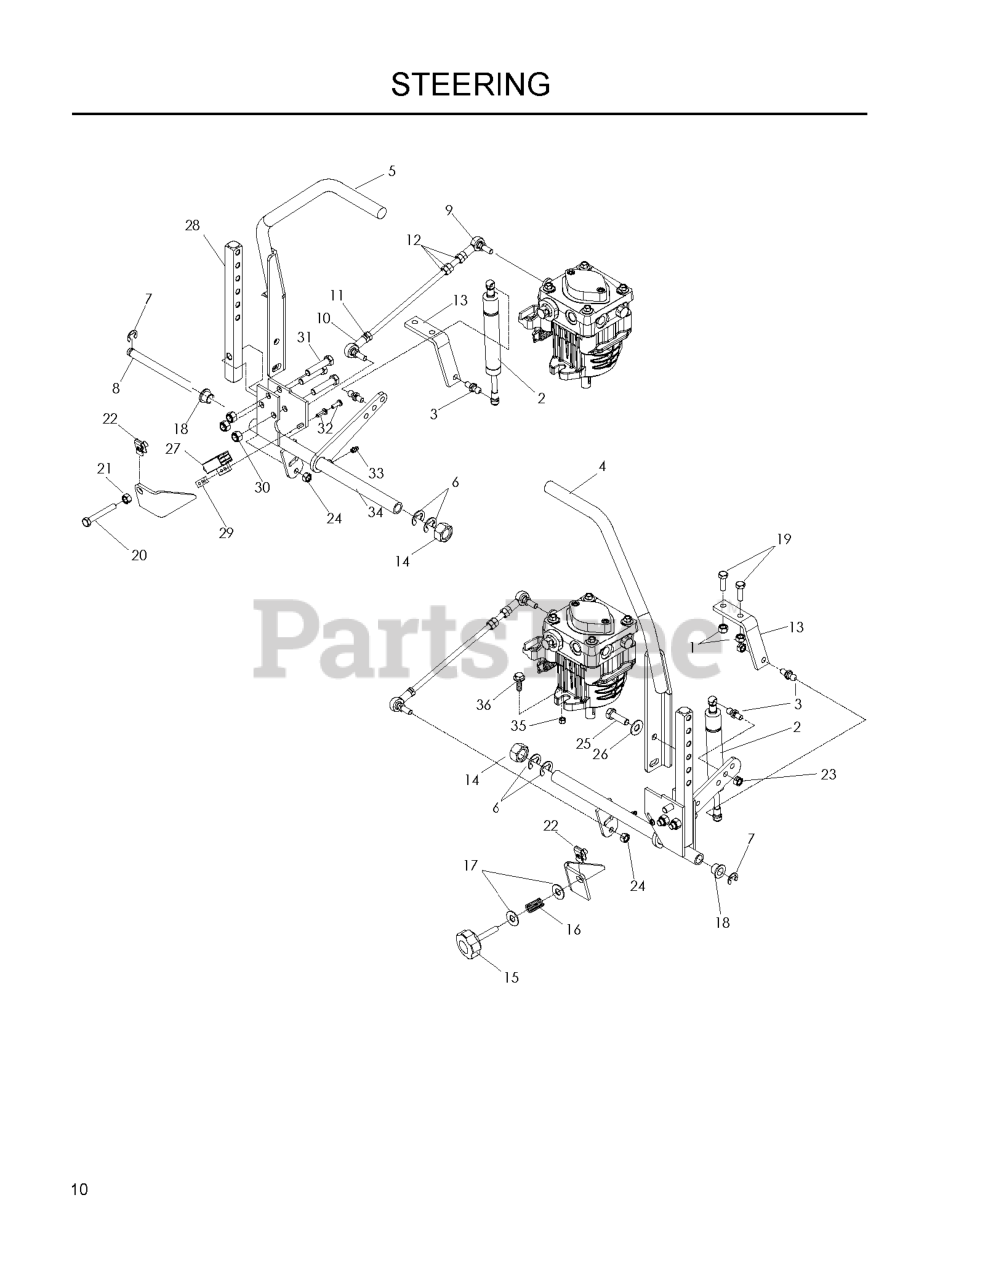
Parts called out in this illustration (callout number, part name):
1	NUT 5/16 NYLOC
2	DAMPENER W/EXT SEAL
3	STUD.BALL.10MM
4	ASSEMBLY, DRIVE LEVER LT
5	ASSEMBLY, DRIVE LEVER RT
6	E-RING 5/8
7	E-RING 1/2 (2 2)
8	CONTROL SHAFT
9	SPHERICAL ROD END, LH
10	SPHERICAL ROD END, RH
11	NUT 5/16F LEFTHAND
13	DAMPENER BRACKET
14	NUT 3/4 X 16 HEX CTR
15	ADJUSTMENT KNOB
16	COMPRESSION SPRING
17	WASHER 5/16 FLAT
19	HCS 5/16C X 1
20	HCS 5/16-18X1-3/4 TPBLT
21	NUT 5/16C HEX
22	U-CLIP 5/16-18 NUT RETAINER
23	NUT 5/16C CENTERLOCK
24	NUT 5/16F NYLOC
25	HCS 3/8-16X1.GRD.5.ZD
26	WASHER, 3/8 DISC SPRING SPEC
27	SWITCH, INTERLOCK
28	CONTROL ARM
29	TAPPED PLATE
30	NUT 3/8-16 NYLOC
31	HCS 3/8-16 X 1 3/4 GR5
32	SCREW #10-24 X 5/8
33	ZERK
34	CONTROL ASM - ADJ, RT
34	CONTROL ASM - ADJ, LT
35	NUT 3/8C CENTERBLOCK
36	4CS 3/8C X 1 SERRATED HEAD
